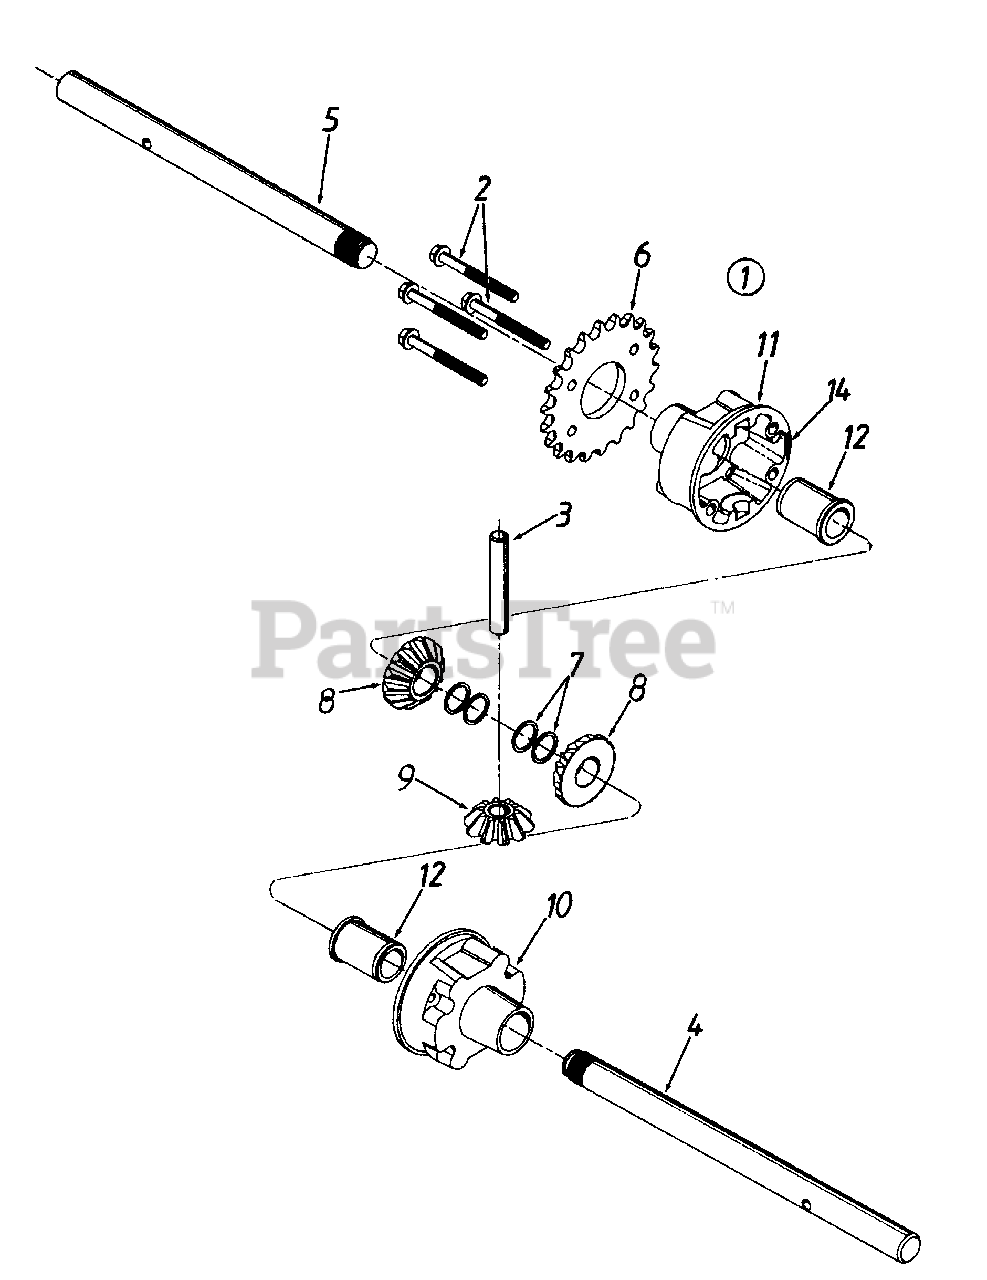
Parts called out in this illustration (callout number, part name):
1	DIFFERENTIAL ASSY COMPLETE
2	SCREW-HEX
3	SHAFT-CROSS
4	AXLE-SHAFT 10.95" LONG
5	AXLE-SHAFT 9.82" LONG
6	SPROCKET 22 T
7	RING-RETAINING (2 PER AXLE)
8	GEAR-DIFFERENTIAL 14T
9	GEAR-DIFFERENTIAL 10T
10	HOUSING-DIFFERENTIAL RH
11	HOUSING-DIFFERENTIAL LH
12	BEARING-FLANGE
